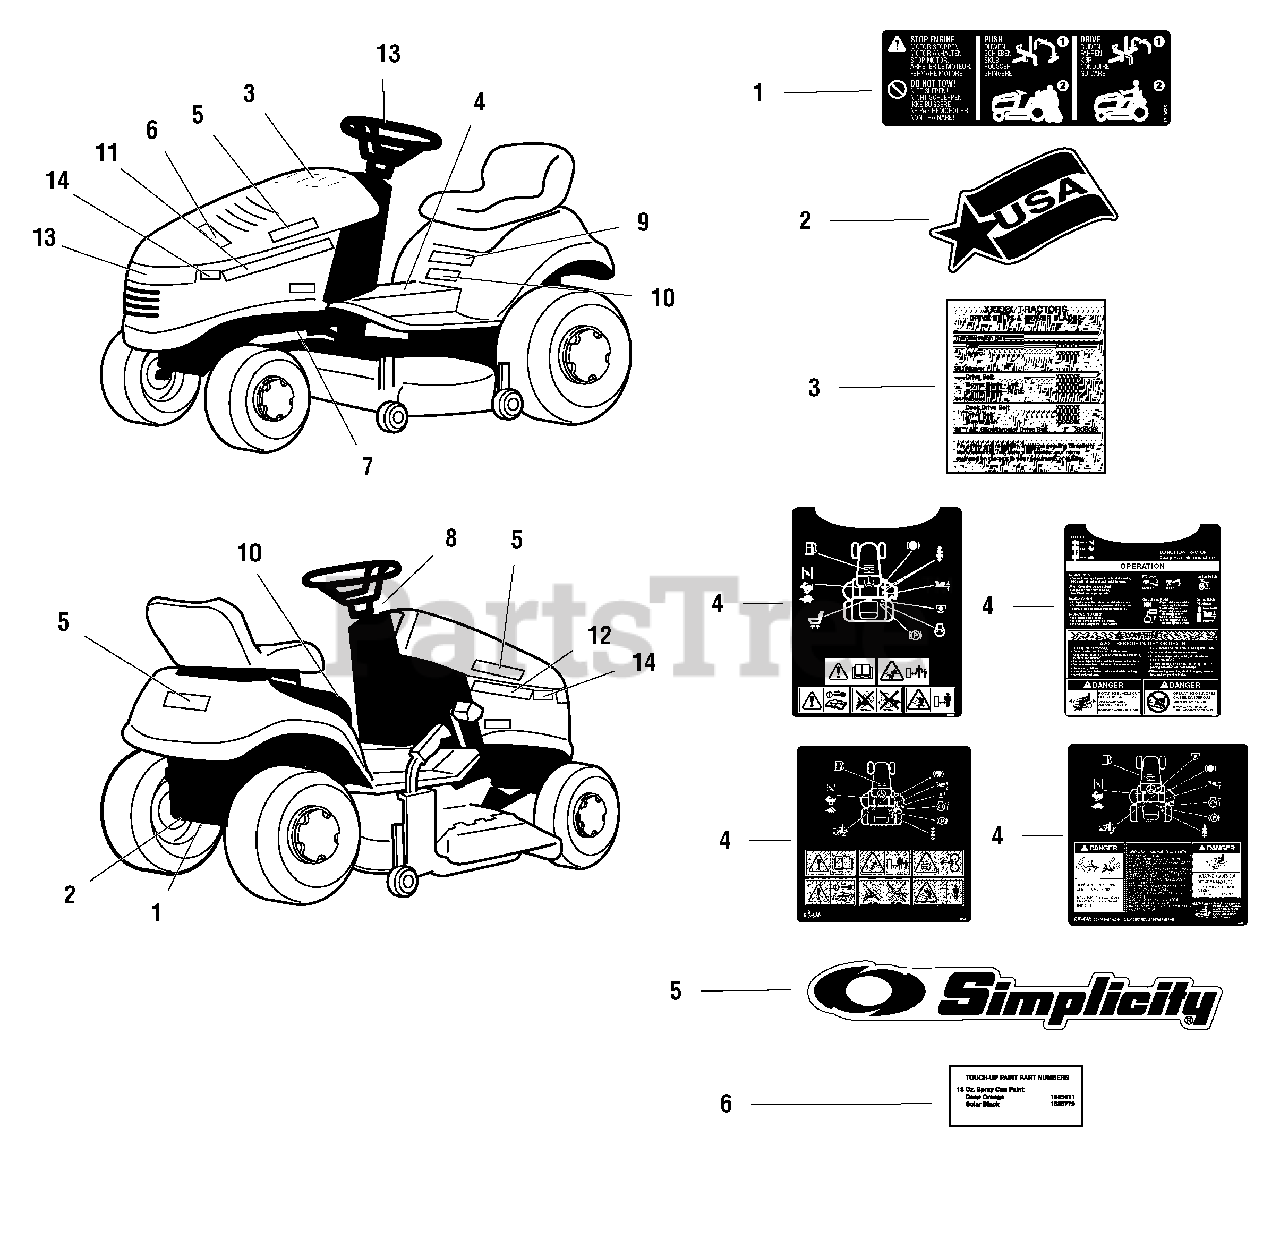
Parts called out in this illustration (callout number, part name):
1	DECAL, Transmission Release Valve
2	DECAL, USA Logo
3	DECAL, Drive Belts, Mower Blades
4	DECAL, Operating Instructions (DOM)(Simplicity)
4	DECAL, Operating Instructions
4	DECAL, Operating Instructions (AGCO)
5	DECAL, Simplicity
6	DECAL, Touch up Paint (Simplicity, AGCO)
6	DECAL, Touch up Paint (Massey)
7	DECAL, Patent
8	DECAL, PTO Control
9	DECAL, Regent
10	DECAL, 18HP (Simplicity)
10	DECAL, 15HP (AGCO)
10	DECAL, 16HP (AGCO)
10	DECAL, 17HP (AGCO)
10	DECAL, 518 (AGCO)
10	DECAL, 2518 (Massey)
11	DECAL, Stripe L.H. (Simplicity)
11	DECAL, Stripe L.H. (AGCO)
11	DECAL, Stripe L.H. (Massey)
12	DECAL, Stripe R.H. (Simplicity)
12	DECAL, Stripe R.H. (AGCO)
12	DECAL, Stripe R.H. (Massey)
13	DECAL, Simplicity, Icon
13	DECAL, AGCO
13	DECAL, Massey Ferguson
14	DECAL, 515 (AGCO)
14	DECAL, 516 (AGCO)
14	DECAL, 517 (AGCO)
